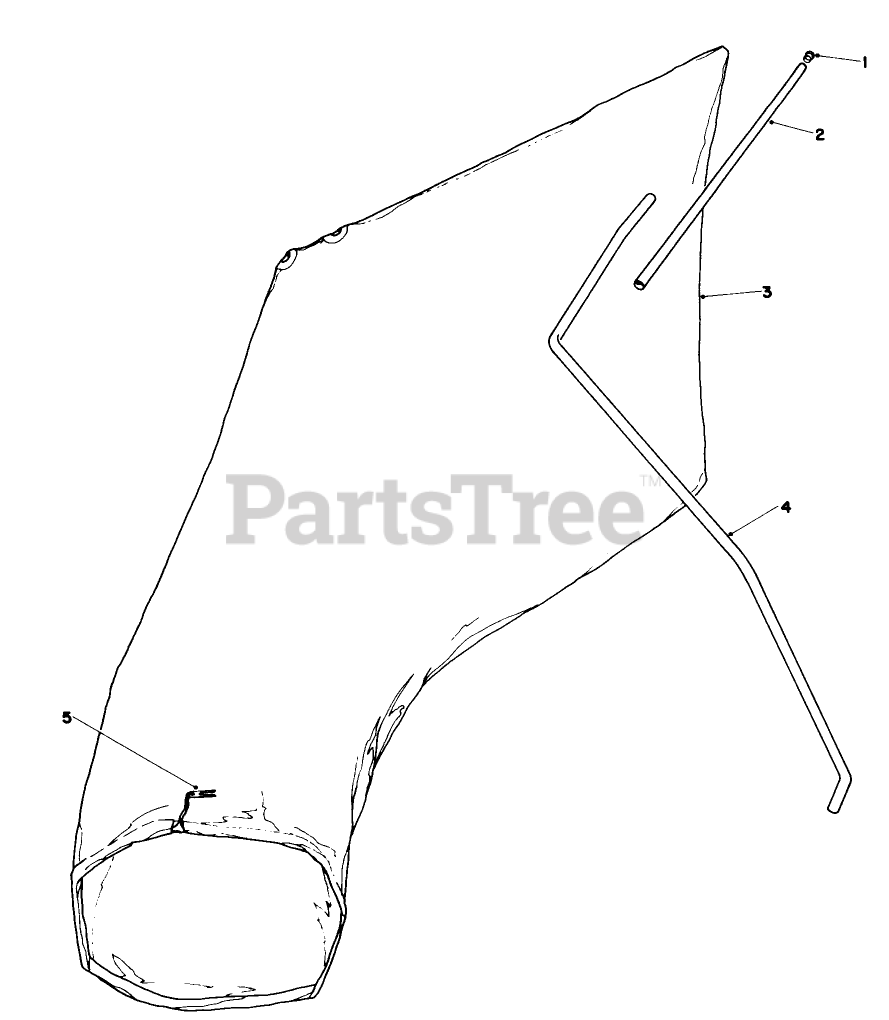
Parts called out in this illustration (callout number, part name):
2	BAG HANGER TUBE
3	Bag (Incl. Ref. #5)
4	Hanger Rod
5	BAG CORD FASTENER
